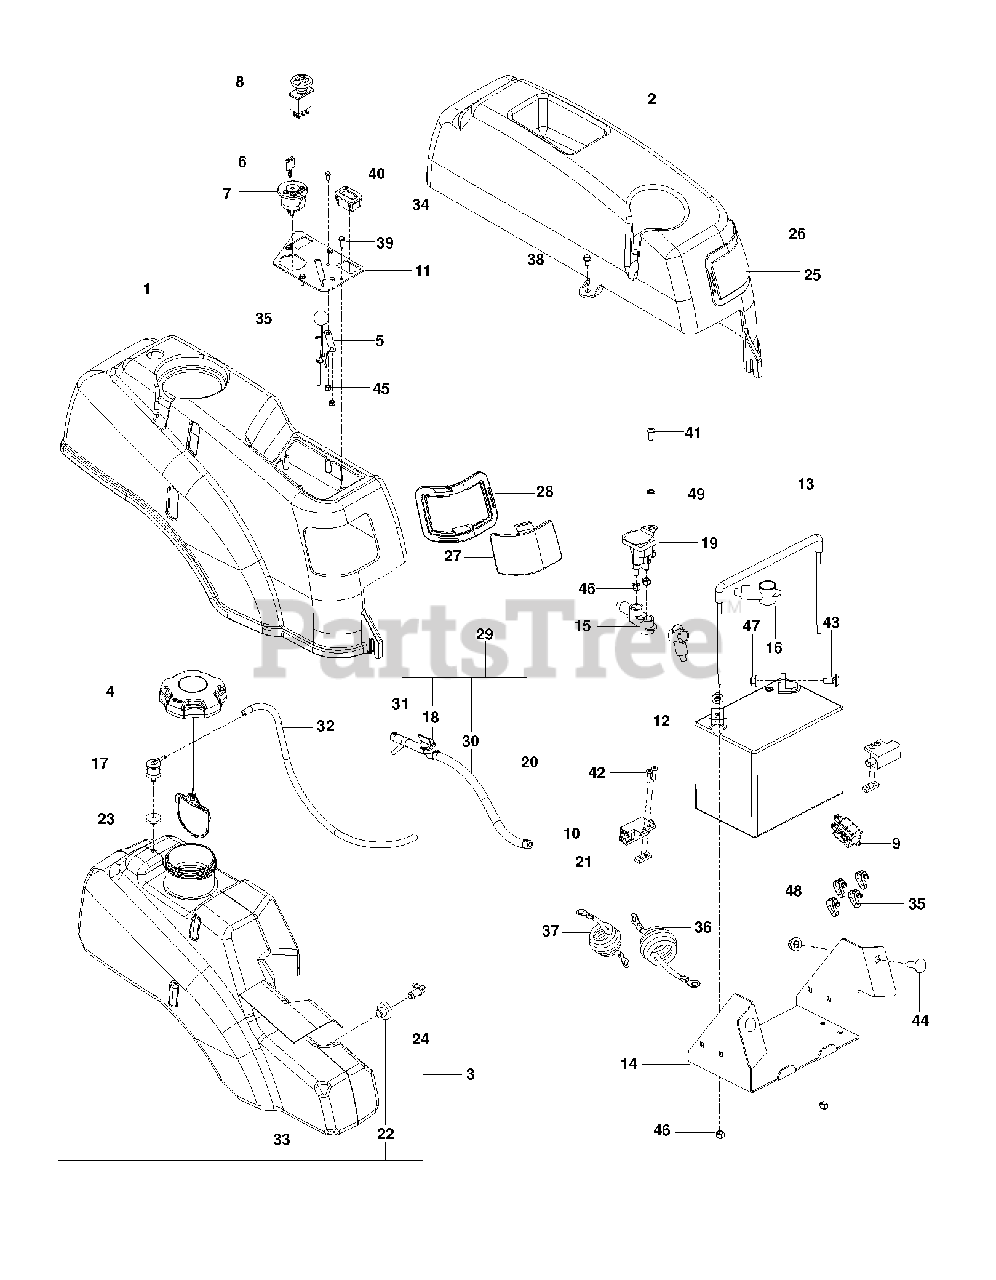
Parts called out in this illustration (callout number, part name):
1	FENDER RT, BLACK
3	TANK.FUEL.ASSEMBLY.LARGE
4	CAP, FUEL
5	CABLE, THROTTLE
6	KEY MLD GEN DELTA
7	IGNITION SWITCH
8	PTO Switch, 8-Terminal STD Black
9	SWITCH, BRAKE 3P
10	SWITCH INTERLOCKT
12	BATTERY, 12 V 330 AMP TBR
13	BATTERY TIE DOWN ASSEMBLY
14	BOX, BATTERY, BLACK
15	TERMINAL COVER-SM
16	INSULATOR
17	VALVE.FUEL.CHECK
18	FUEL VALVE
19	SOLENOID.W/BRASS.PLUNGER
20	HOSE CLAMP
21	PLATE NUT ZTR
22	RUBBER GROMMET
23	GROMMET, CHECK VALVE
24	STEM, FUEL TANK
25	PANEL, LT
26	RING, LT BLK
27	PANEL, RT, BLK
28	RING, TRIM, RT-BLK
29	FUEL LINE ASSY
30	GAS LINE 10"
31	FUEL LINE 2.5"
32	HOSE.FEEL.3/16" X 20"
33	SHIELD, HEAT
34	GUAGE.SRVCMNDR.HRMTR.
35	KNOB ROUND BALL
36	CABLE POSITIVE, LONG
37	BATTERY CABLE, NEGATIVE
38	BOLT 1/4-20 X 1/2 HWST
39	SCR #10-12X3/4 HEX WAS HD ZD
40	HCS #10-24 X 1/2
41	SCR 1/4-20 X 5/8 BTN SKT HD ZD
42	SCR #10-24 X .75 SKT HD BLK
43	BOLT 5/16C X 3/4" CARRIAGE
44	RHSNB 3/8C X 1
45	NUT 10-24 NYLOC
46	NUT 1/4-20 NYLOC
47	5/16-18 NYLOC FLANGE NUT
48	NUT 3/8-16 HEX FLG NYLOC ZD
49	WASHER 1/4 INT TOOTH
